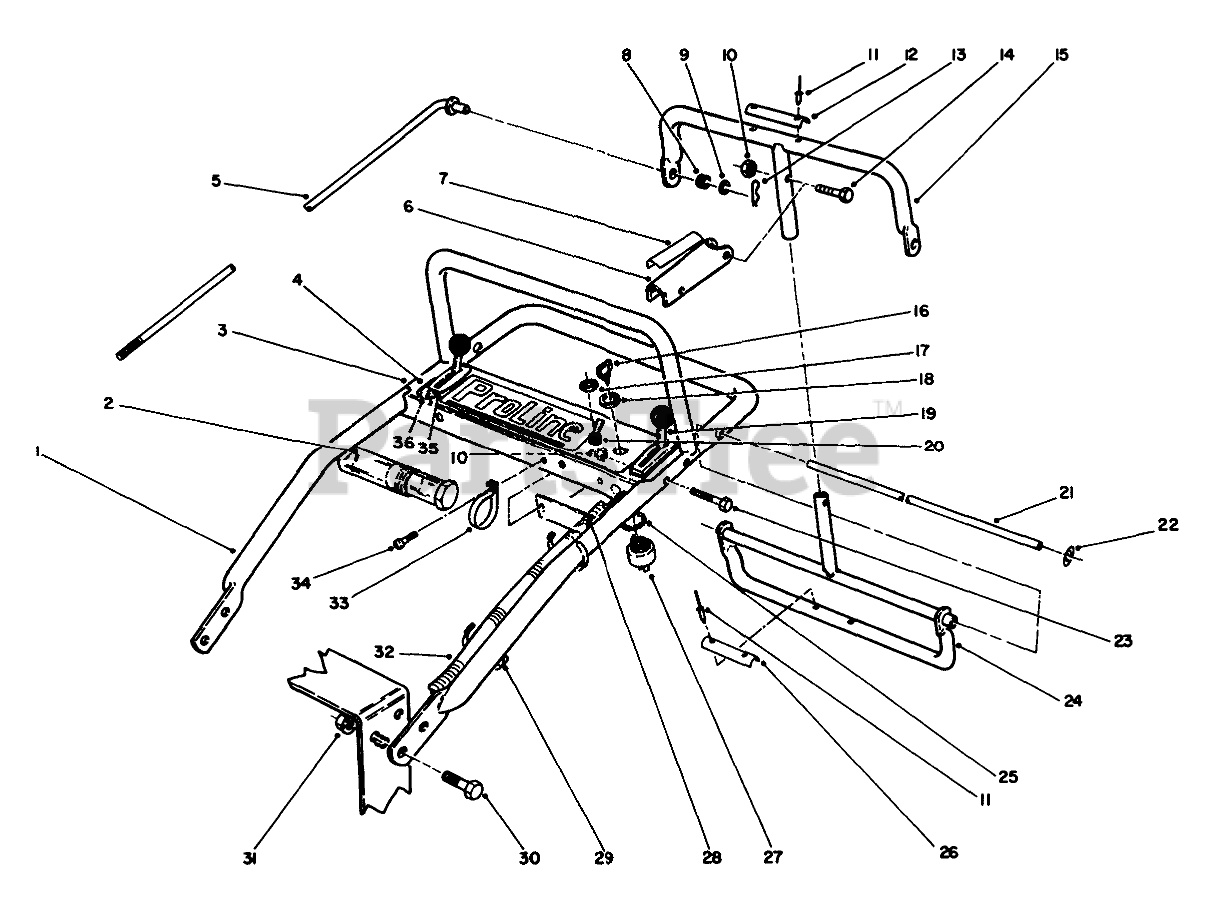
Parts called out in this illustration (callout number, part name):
1	Handle-Upper
2	TUBE-MANUAL
3	CONTROL PANEL B
4	Decal-Proline
5	CONTROL ROD B
6	Lever-Parking Brake
7	DECAL-LEVER, PARKING
8	GROMMET-RUBBER
9	WASHER-FLAT
10	NUT-LOCK, NI
11	RIVET-BLIND
12	DECAL-CONTROL BAR
13	PIN-COTTER
14	SCREW-SHH
15	Bar-Control
16	KEY-IGNITION
17	NUT
18	NUT-HH
19	THROTTLE CONTROL
20	Switch-Clutch (Incl. Ref. #17)
21	PIVOT ROD
22	NUT-PUSH-ON, CIRCULAR
23	SCREW-SHH
24	Control Pivot
25	WASHER-TOOTH, INTERNAL
26	DECAL-REVERSE HANDLE
27	Switch-Ignition (Incl. Ref. #16, 18, & 25)
28	PANEL-BOTTOM
29	TIE-CABLE
30	SCREW-HHF
31	NUT-HF
32	16 HP WIRING HARNESS
33	CLAMP-R
34	SCREW-HWHTF
35	CHOKE CONTROL
36	SPACER
